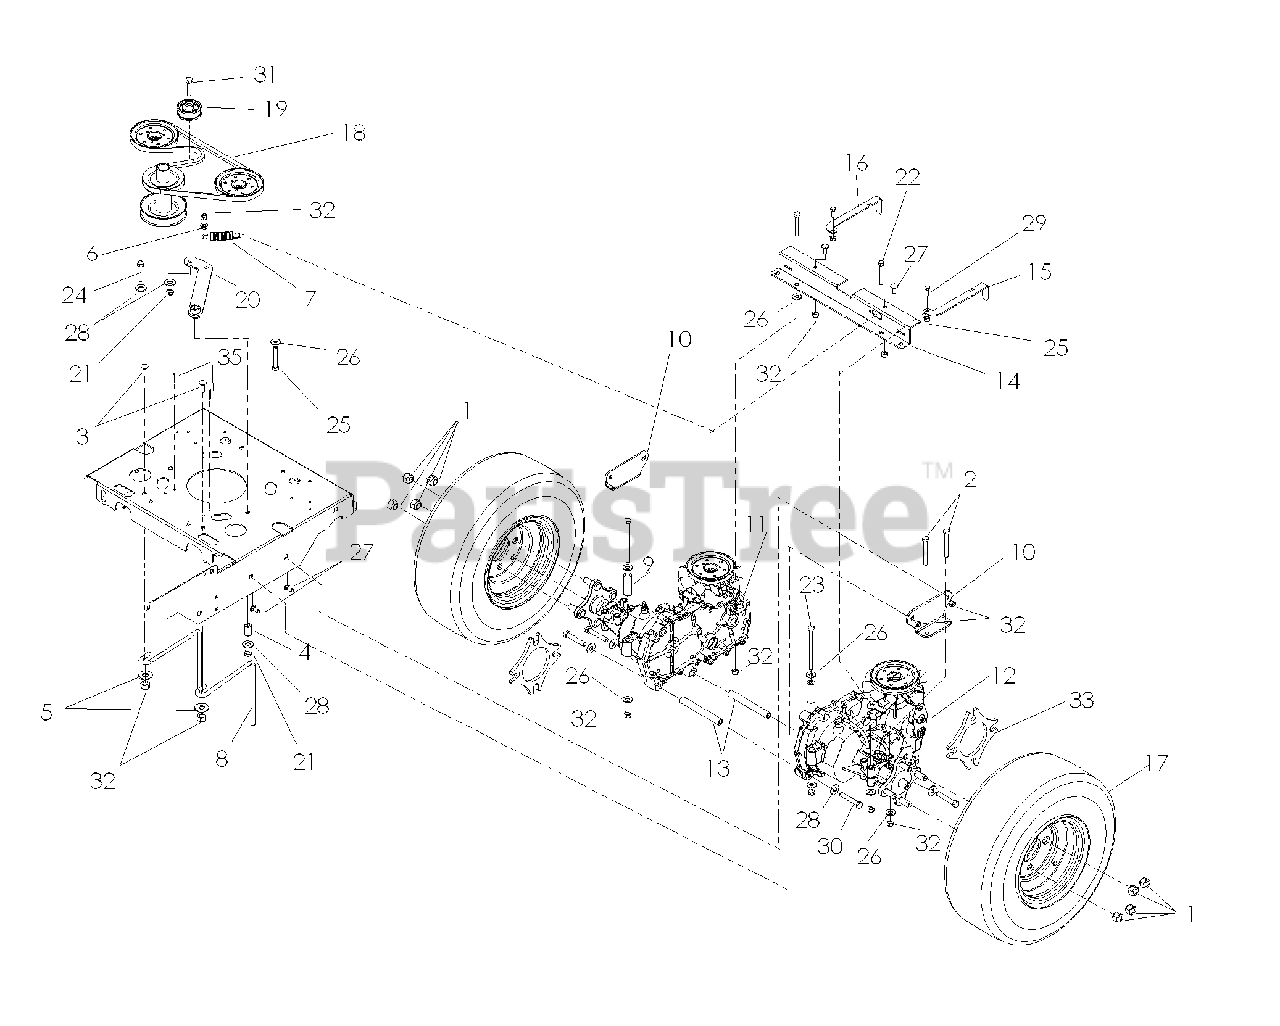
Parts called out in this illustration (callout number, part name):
1	LUG NUT 1/2F
2	HCS 5/16C X 2-3/4
3	RHSSNB 5/16C X 1.0
4	BUSHING
5	WASHER 5/16 FLAT
6	5/16-18 FLANGED L-NUT
7	SPRING - 3.50
8	BELT GUIDE
9	SPACER HYDRO MT.
10	HYDRO MT. PLATE
11	HG_HYDRO RH
12	HG_HYDRO LH
13	HYDRO SPACER
14	REAR HYDRO MT.
15	RELEASE LEVER LH
16	RELEASE LEVER RH
17	REAR WHEEL AND TIRE
18	BELT 30 ZEZT
19	PULLEY IDLER
20	IDLER WLDT.
21	NUT HEX 3/8-16 NYLON, THIN
22	CAPSCREW
23	CAPSCREW 5/16 X 4-1/2 HED HEAD
24	BOLT, HCS 3/8-16X1-3/4
25	NUT 1/4-20 NYLOC
26	FLAT WASHER 5/16 SAE
27	BOLT 5/16C X 3/4" CARRIAGE
28	WASHER 3/8 FLAT
29	HCS 1/4C X 3/4 HCS
30	HCS 3/8C X 2 1/4
31	HCS 3/8C X 1 1/2
32	NUT 5/16 NYLOC
33	SPACER, WHEEL
